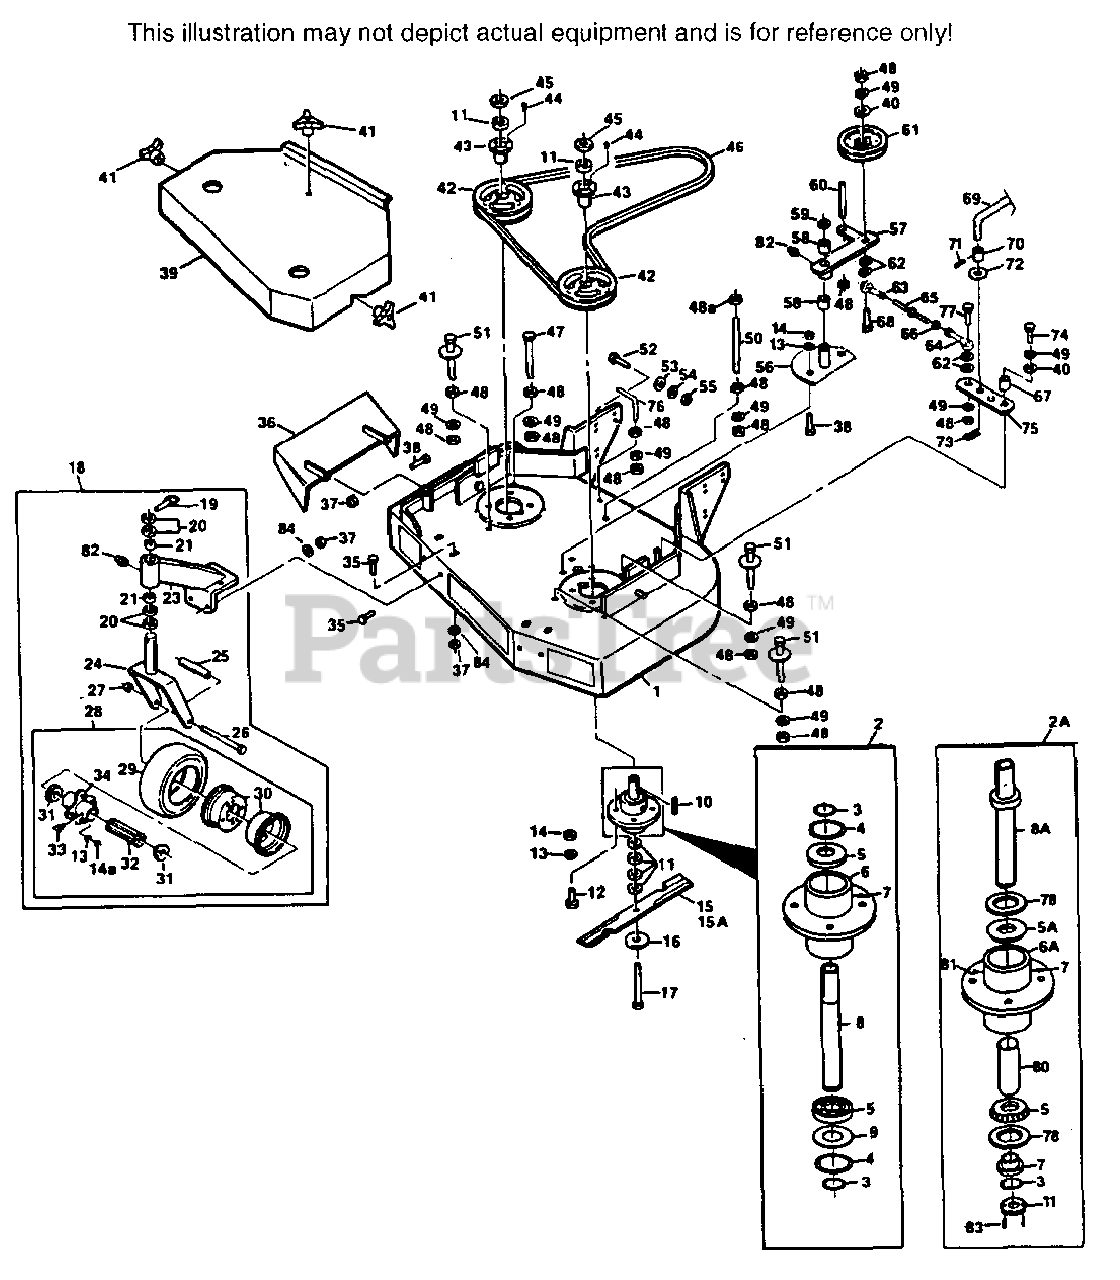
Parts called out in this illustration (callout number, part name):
1	CUTTER DECK(INCLUDES DECALS)
2	CUTTER SPINDLE ASSY.(INCLUDES ITEMS 3-9)
2A	CUTTER SPINDLE ASSY.
3	RETAINING RING, 1" EXT.-INVERTED
4	RETAINING RING, 2-7/16 INT.BSC
5	BEARING, SPINDLE
5A	TAPERED BEARING
6	SPINDLE HOUSING
6A	SPINDLE HOUSING
7	GREASE FITTING, STR., 5/16 SERR
8	SPINDLE, CUTTER BLADE
8A	SPINDLE SHAFT
9	WASHER, 1-5/16 X 2-7/16 X 16 GA.
10	KEY, 1/4 X 1/4 X 2
11	SPACER, CUTTER BLADE - SMALL
15	CUTTER BLADE 18"
15A	CUTTER BLADE 18" HI LIFT
16	FLAT WASHER, 5/8 W
17	HEX HD. BOLT, 5/8-11 X 9-1/2
18	CASTER ASSEMBLY(INCLUDES ITEMS 19-28)
19	QUICK PIN
20	SPACER, CASTER YOKE, 1/2" LONG
21	BRONZE BEARING
23	SUPPORT ASSEMBLY(INCLUDES ITEMS 21, 82)
24	CASTER YOKE
25	SLEEVE, CASTER WHEEL BRG.
26	HEX HD. BOLT, 1/2-13 X 5-1/2
28	WHEEL ASSY.(INCLUDES 13-14A, 29-34)
29	TIRE ONLY CASTER WHEEL
30	RIM PAIR, CASTER WHEEL
31	RETAINER, BEARING, CASTER WHEEL
32	ROLLER BEARING, CASTER WHEEL
33	GREASE FITTING, 45' 1/4-28
34	HUB ASSEMBLY
36	DISCHARGE CHUTE
37	HEX NUT, 5/16-18 ELASTIC STOP
39	BELT COVER ASSEMBLY(INCLUDES DECAL)
40	WASHER, 25/64 X 15/16 X 12 GA.
41	WING NUT, 3/8-16
42	PULLEY(INCLUDES ITEMS 43-44)
43	TAPERED HUB
46	BELT, BLADE DRIVE
50	SUPPORT, BELT COVER
51	BELT GUIDE
53	WASHER, 15/32 X 59/64 X 16 GA.
55	HEX NUT, 7/16-14 ELASTIC STOP
56	IDLER PIVOT
57	IDLER ARM ASSY.(INCLUDES ITEMS 82 & 58)
58	BRONZE BEARING(GRAY)
59	RETAINING RING, 1 1/8" EXT,-"E"
61	IDLER PULLEY, BELT CLUTCH
63	ROD END - L.H. THD(SILVER)
64	ROD END - R.H. THD(GOLD)
65	LINK, TURNBUCKLE
67	SLEEVE, CLUTCH ROD
69	BLADE CLUTCH ROD, LOWER
70	SLEEVE, CLUTCH ROD
72	WASHER, 33/64 X 1 X 16 GA.
73	HAIR PIN, LARGE
75	CAM LINK
76	BELT GUIDE
78	SEAL, CUTTER SPINDLE
79	SPINDLE BUSHING
80	SLEEVE, CUTTER SPINDLE
81	RELIEF FITTING, CUTTER SPINDLE
82	GREASE FITTING, CUTTER SPINDLE
